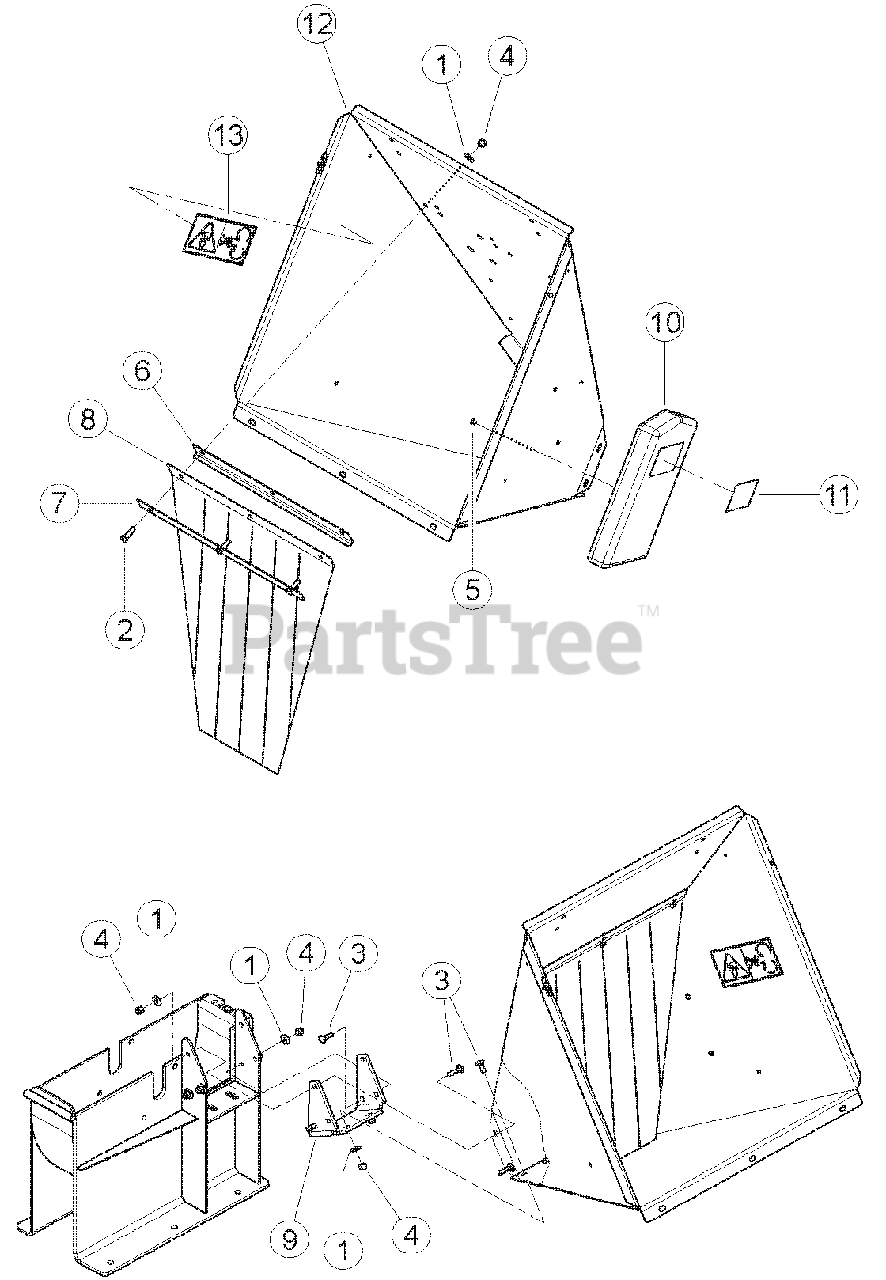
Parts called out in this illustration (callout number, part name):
1	WASHER, 3/8 FLAT ZP
2	BOLT, 3/8 X 1 CRG GR5 NC ZP
3	BOLT, 3/8 X 1-1/2 CRG GR5 NC ZP
4	BOLT, 3/8 X 1-1/4 HEX HD GR5 ZP
5	BOLT, 3/8 X 1-1/4 CRG GR5 NC ZP
6	NUT, 3/8 NE NYLOCK ZP
7	RIVET, 1/4 X 1/2 DOME HD BLIND SS
8	ANGLE, FLAP ANCHOR
9	STRIP, FLAP RETAINER
10	FLAP, CHIPPER CHUTE
11	BRACKET, CHUTE MOUNT
12	ASSEMBLY, MANUAL CONTAINER SERVICE PART
13	DECAL, MUTILINGUAL MANUAL
14	ASSEMBLY, 5 INCH CHIPPER CHUTE SERVICE PART
15	DECAL, BLADE DANGER ISO
